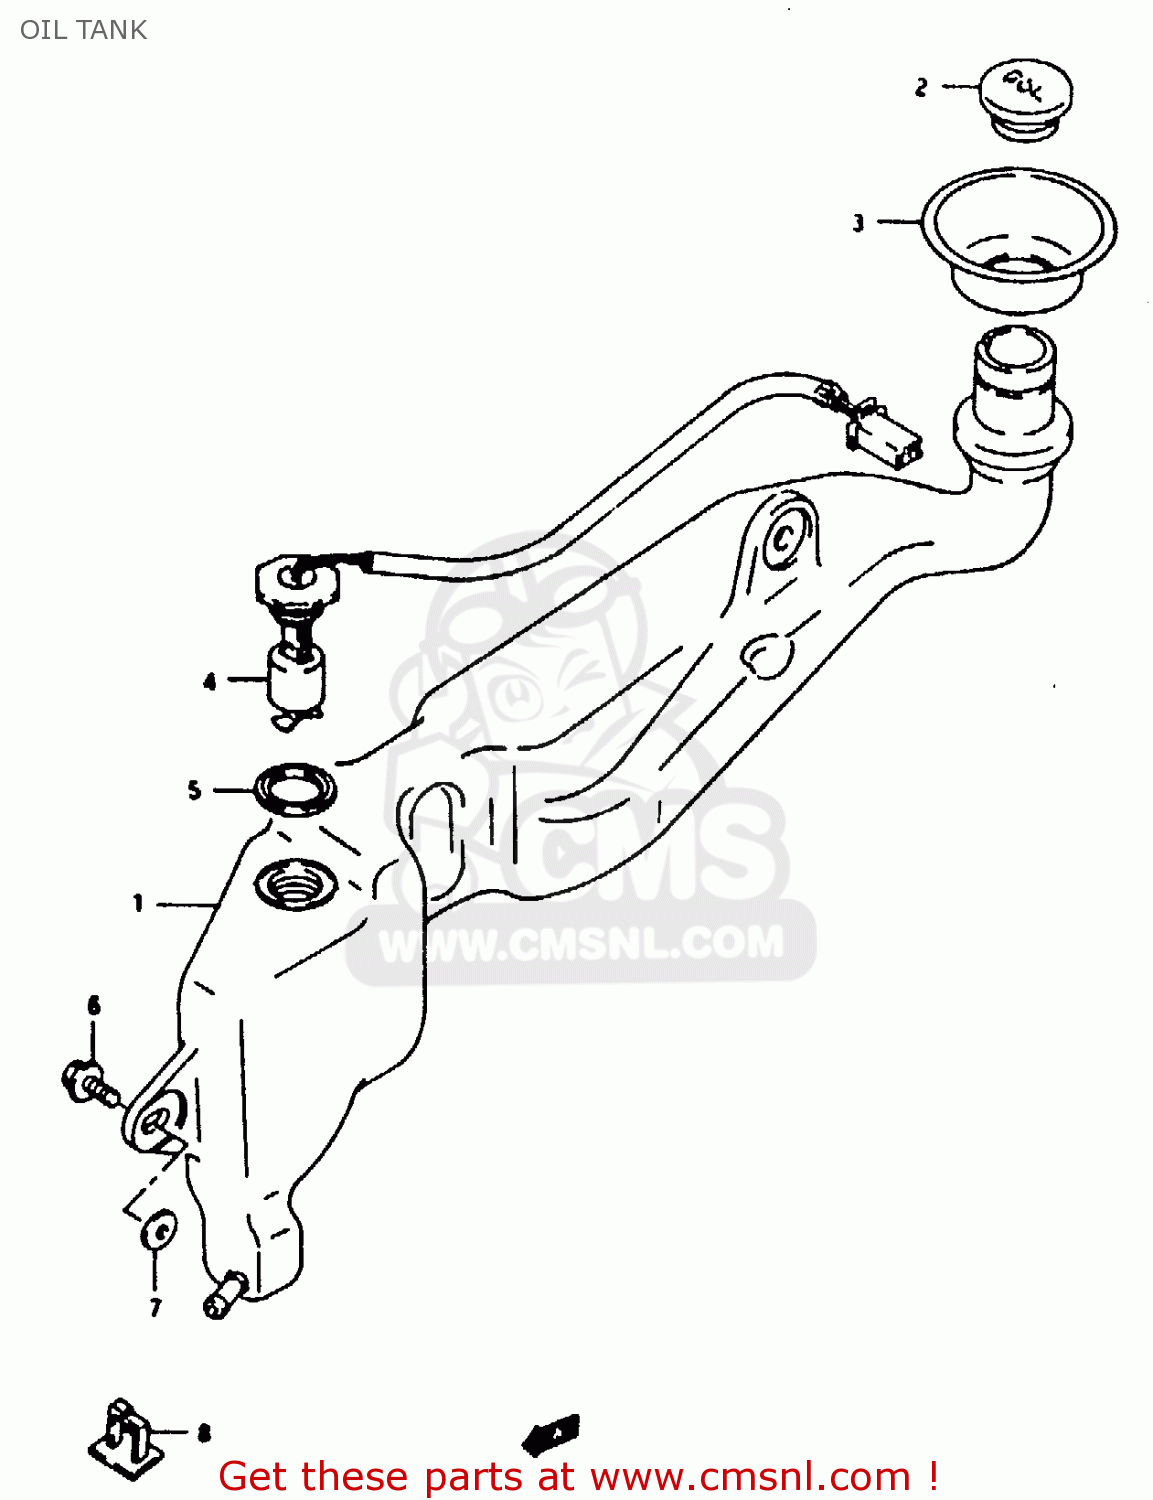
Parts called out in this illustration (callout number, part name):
1	TANK,OIL
2	CAP,OIL TANK
3	RUBBER,OIL TANK INLET
4	SWITCH ASSY, OIL LEVEL
5	GASKET (NAS)
6	BOLT(6X20)
7	WASHER(6.5X18X1)
8	CLAMP
